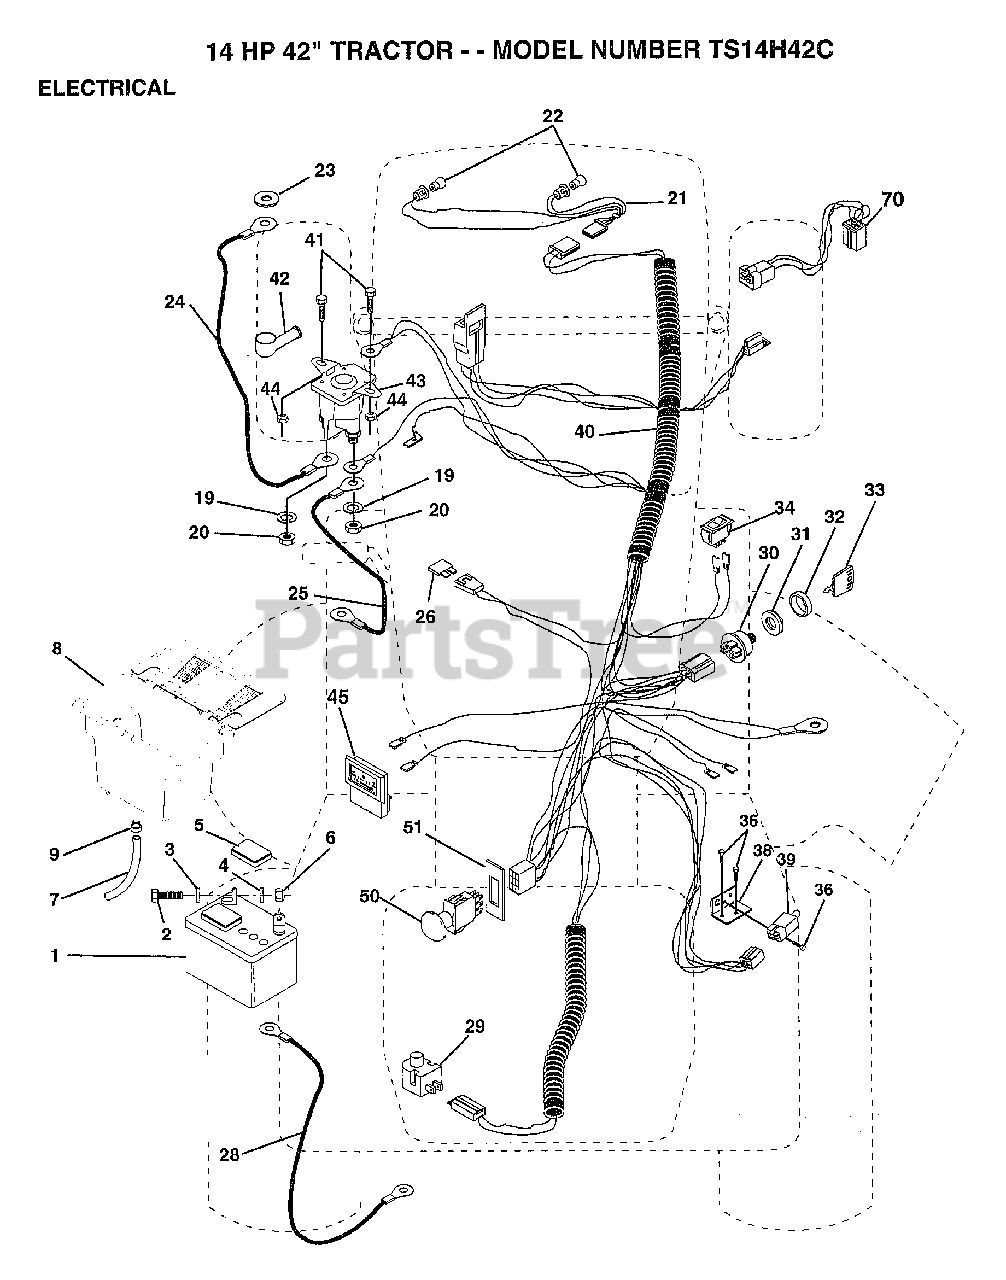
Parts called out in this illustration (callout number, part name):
2	BOLT LT
3	WASHER
4	LOCKWASHER
5	"CAP,BATTERY "
7	TUBE T
9	PLATE T
20	NUT
21	"HARNESS,LIGHT SOC"
22	HEADLAMP BULB
23	LOCKWASHER
24	CABLE-BATTERY T
26	FUSE HYT
28	CABLE T
29	SWITCH SEAT
32	COVER KEY SWITCH
33	KEY MLD GEN DELTA
34	SWITCH LT
36	SCREW
38	BRACKET SWITCH IN
39	SWITCH INTERLOCKT
40	HARNESS.IGN.PTO
41	BOLT HXHD FIN
44	NUT HXKEP 1/4X20
45	AMMETER
51	RING RETAIN PTO
70	HARNESS ENG 11GA
